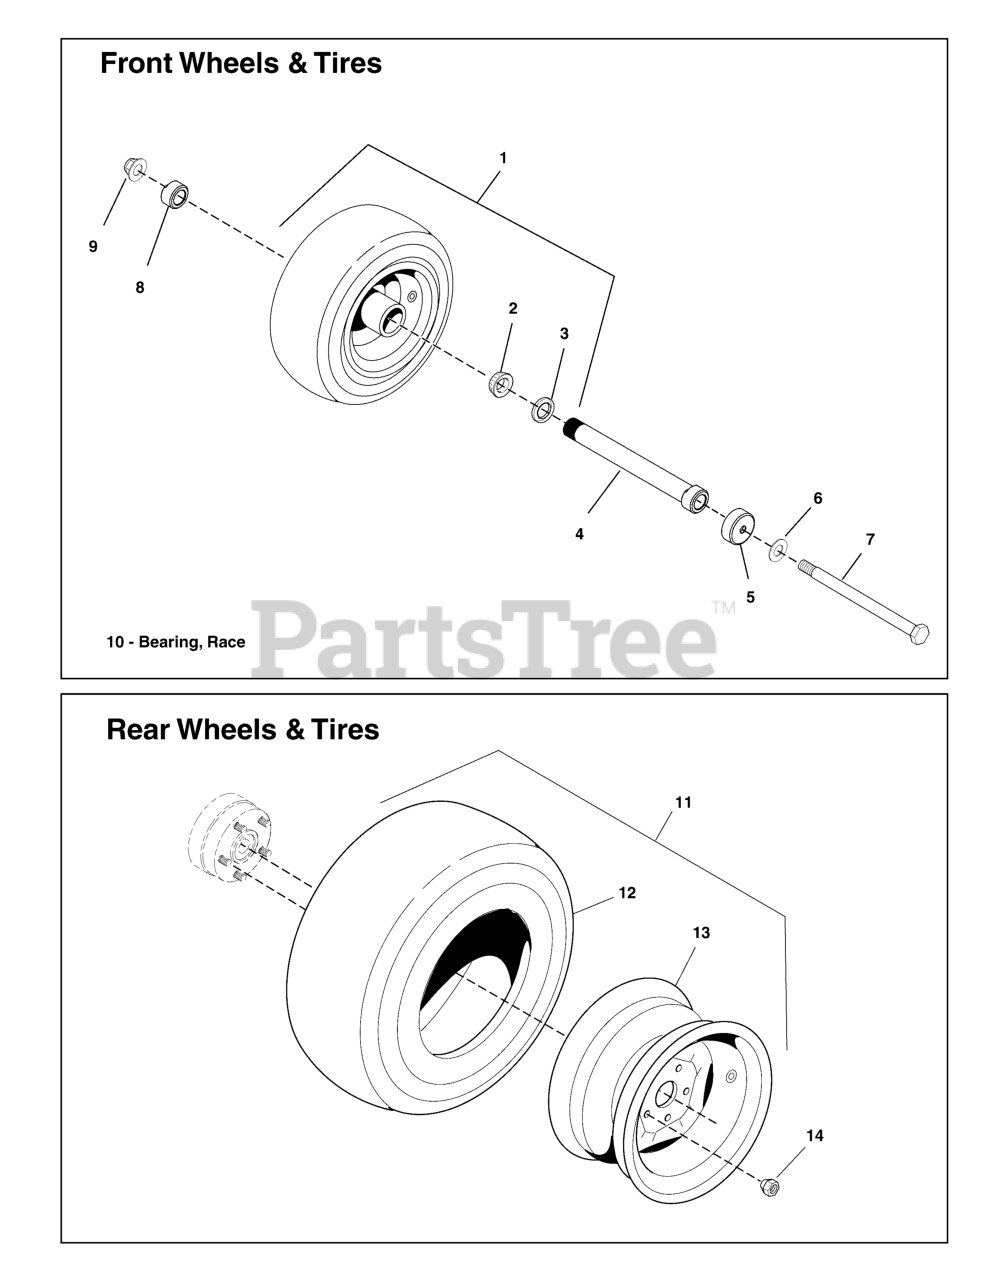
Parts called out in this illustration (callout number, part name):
1	* FLAT-FREE TIRE ASSEMBLY, 13 x 5.0 - 6
2	BEARING, Tapered Roller
3	SEAL, GREASE
4	BEARING ADJUSTER, SPACER, 6.062 LG
5	DEBRIS, COVER, CASTER WHEELS
6	WASHER, 1/2 SAE
7	BOLT, 1/2-13 X 8 GD5 YZ (NLA)
8	NUT, BEARING ADJUSTER, AXLE
9	NUT, Hex Flange, Nylock, 1/2-13
10	BEARING, RACE
11	TIRE WHEEL ASM, 23X10.50-12, TURF MASTER
12	TIRE
13	WHEEL, 12 X 8.5, 5/4.5, 1.3 OFFSET (SV)
14	NUT, 1/2-20, FOR WHEEL BOLT SILVER
